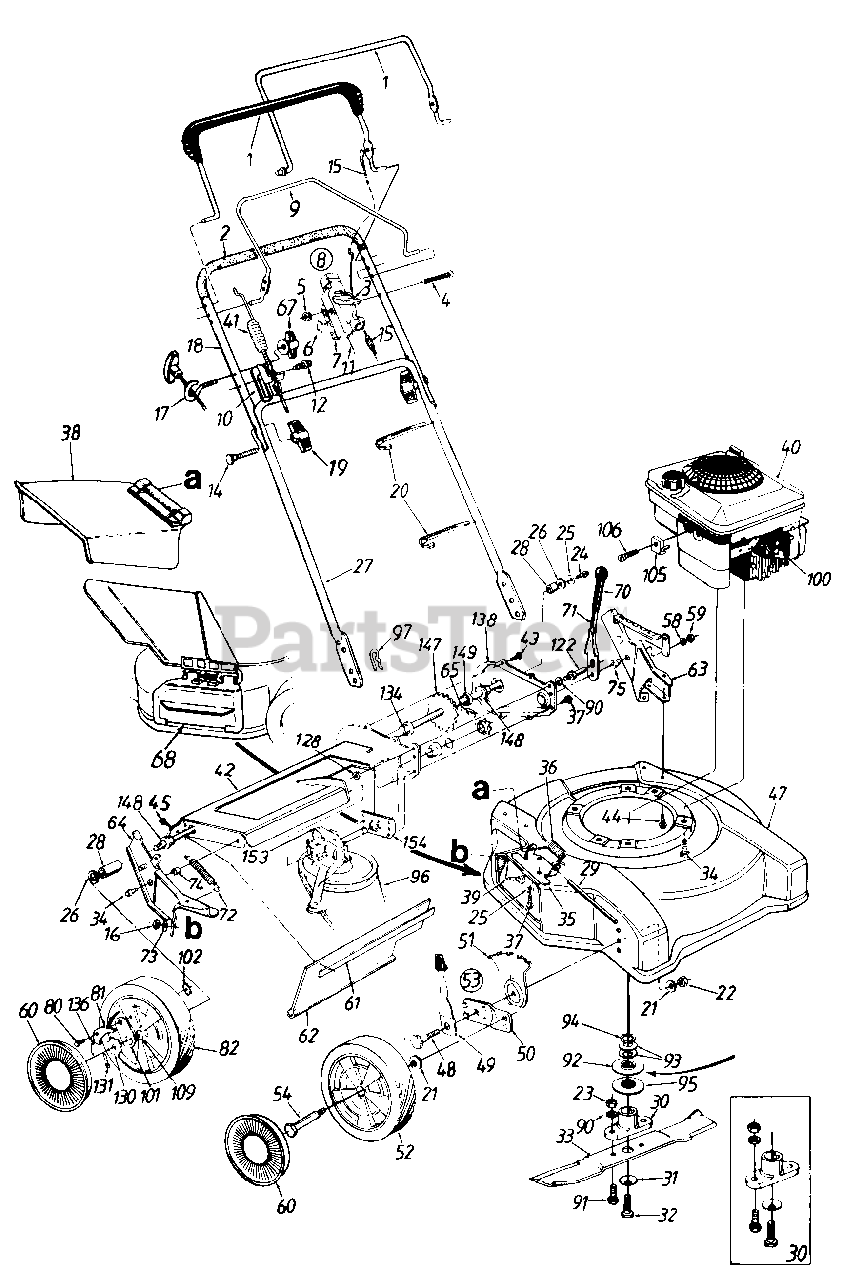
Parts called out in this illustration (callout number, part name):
3	Throttle Lever
4	Oval C-Sunk Scr.
5	Hex L-Nut 1/4-20 Thd.
6	Spr. Wash. .66" I.D.
7	Throttle Body
8	Throttle Box Comp.
11	Throttle Cable 55" Lg.
12	Hex Wash. AB-Tap Scr. 5/16 x .75" Lg.
14	Curved Hd. Bolt 5/16-18 x 2"
15	Control Cable 39" Lg.
16	Hex Nut 5/16-18 Thd.
20	Cable Tie
21	Bell-Wash. .38" I.D. x .88"
22	Hex Nut 3/8-16 Thd.
23	Hex Nut 3/8-24 Thd.
24	Hex Bolt 1/4-20 x .62" Lg. (Grade 5)
25	Bell-Wash. 1/4" I.D.
26	Fl-Wash. .531" I.D. x .93"
28	Spacer .513" I.D. x .703"
29	Hinge Pin
30	Blade Adapter Kit
31	Bell-Wash. .39" I.D.
32	Hex Bolt 3/8-24 x 1.5" Lg.
33	22" Blade
34	Hex L-Wash. Hd. Scr. 3/8-16 x 1.0" Lg.
35	Adapter Plate
36	Torsion Spring
37	Hex Self-Tap Scr. 1/4-20 x .5"
38	Chute Deflector Ass'y.
39	Carriage Bolt 5/16-18 x .62" Lg.
40	Engine
41	Drive Cable - 41.5" Lg.
44	Hex Wash. Hd. B-Tap Scr. 5/16-18
45	Hex AB-Tap Scr. 1/4 x .62"
49	Spring Lever Ass'y. w/Knob
50	Pivot Bar
51	Height Adj. Plate
52	Wheel Ass'y. Comp.
53	Height Adj. Ass'y. Comp. - R.H.
54	Shld. Bolt .498" Dia. x 1.45"
58	Fl-Wash. .385" I.D. x .87"
59	Hex Patch L-Nut 3/8-24 Thd.
60	Hub Cap
61	Retaining Strip
63	L.H. Handle Wheel Brkt. Ass'y.
64	R.H. Handle Wheel Brkt. Ass'y.
65	#48 Chain .5" Pitch x 30 Links
67	Wing Nut 1/4-20 Thd.
68	Mulching Baffle
71	Height Adj. Lever
72	Ext. Spring .5" O.D. x 3.8" Lg.
73	Bell-Wash. 5/16" I.D.
74	Spacer .383" I.D. x .503"
75	Shld. Spacer .5" Dia.
80	Shld. Scr. .342" Dia. x .268"
81	Pawl
82	Wheel Ass'y. Comp.
90	L-Wash. 3/8" I.D.
91	Hex Bolt 3/8-24 x 1.0" Lg.
92	Upper Pulley Half
93	Bell-Wash. 7/8" I.D.
94	Crankshaft Spacer
95	Lower Pulley Half
96	"V"-Belt
97	Hairpin Clip
100	Spark Plug Boot
101	Pawl Plate
102	Weld L-Nut 1/4-20 Thd.
105	Cable Clamp
106	Hex Wash. Hd. Scr. #10-32 x .62" Lg.
109	Sleeve Brg. 1/2" I.D.
122	Shld. Pin 3/8-24 x 1.43" Lg.
128	Hex Jam Nut 3/8-24 Thd.
130	Ratchet Wheel 1.62" O.D.
131	Cotter Pin 1/8" Dia.
134	Hex Flange Bearing
136	Spring - Nylon
148	Hex Flange Bearing
149	Fl-Wash. .531" I.D. x .93"
153	Transmission Comp
